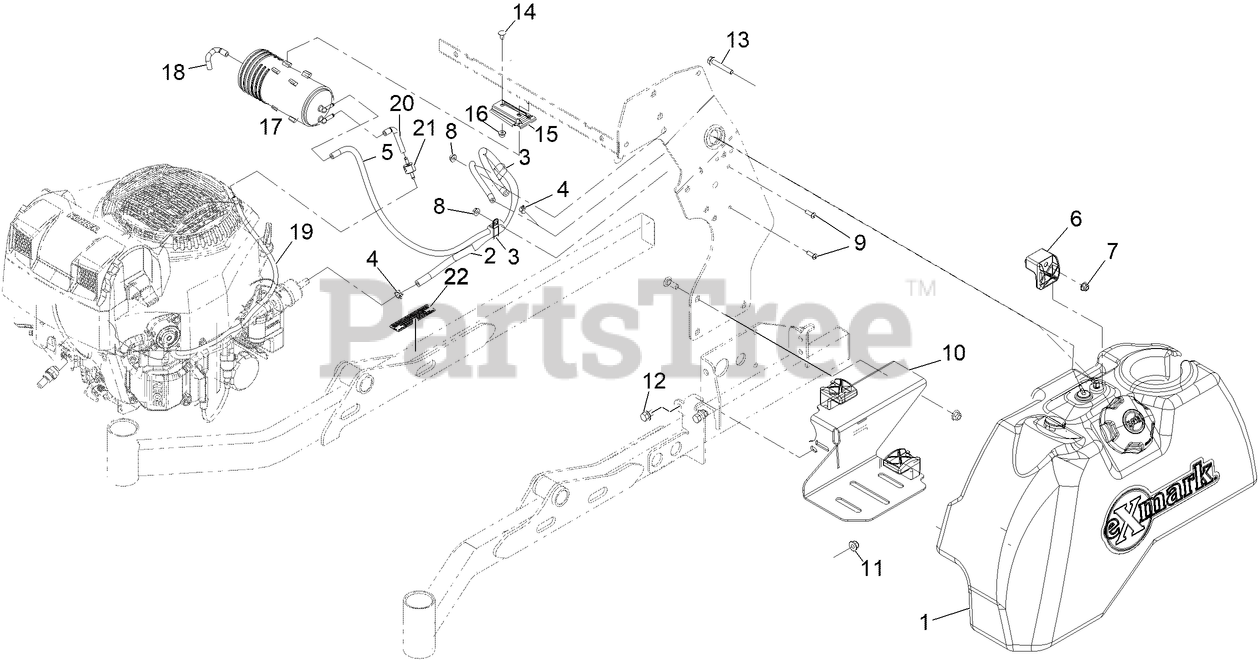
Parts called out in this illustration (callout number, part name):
1	ASM, FUEL TANK 8 GAL
2	HOSE-FUEL
3	CLAMP-R, DOUBLE TUBE
4	CLAMP-HOSE
5	HOSE-FUEL
7	NUT-HF, NI
9	SCREW-HSBH
10	Bracket-Fuel Tank
11	NUT-HF, NI
12	Screw-HH Flg 3/8-16 X 3/4
13	SCREW-HHF
14	SCREW-CARR
15	BRACKET-CANISTER, CARBON
17	CANISTER-CARBON, 800CC
18	HOSE-VENT, FORMED
19	Hose, Emissions
20	HOSE-VENT, FORMED
21	VALVE-CHECK, VACUUM
22	DECAL-ARRESTOR, SPARK
